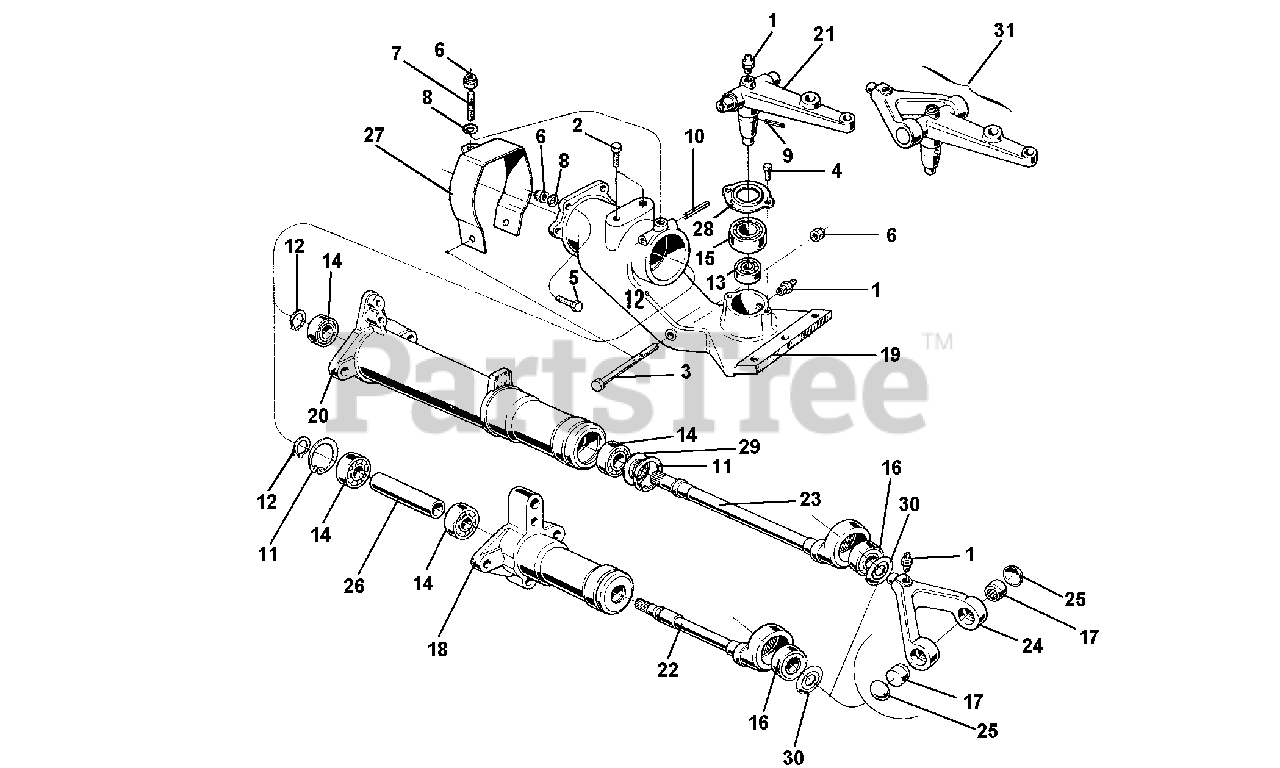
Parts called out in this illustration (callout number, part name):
1	LUBRICATOR M10
2	SCREW TE M8 X 12
3	SCREW TE M8 X 100
4	SCREW TE M6 X 16
5	SCREW M8 X 25
6	NUT, SELF LOCKING M8
8	WASHER, FLAT 8.4
9	PIN, LOCKING 4 X 35
10	LOCKING PIN 6 X 60
11	CIRCLIP, INTERN. D 47
12	CIRCLIP, EXTERN. D 20
13	BEARING 15 X 35 X 11 6202
14	BEARING 20 X 47 X 14 6204 2RS ST
17	BUSH PIT VIOL 44855000
18	BUSHING WITH FLANGE
19	BAR SUPPORT
21	REINFORCED BLADE CRANK
22	ECCENTRIC SHAFT
23	LONG ECCENTRIC SHAFT
27	ECCENTRIC PROTECTION
28	COVER, BEARING
31	CRANK WITH FORK
